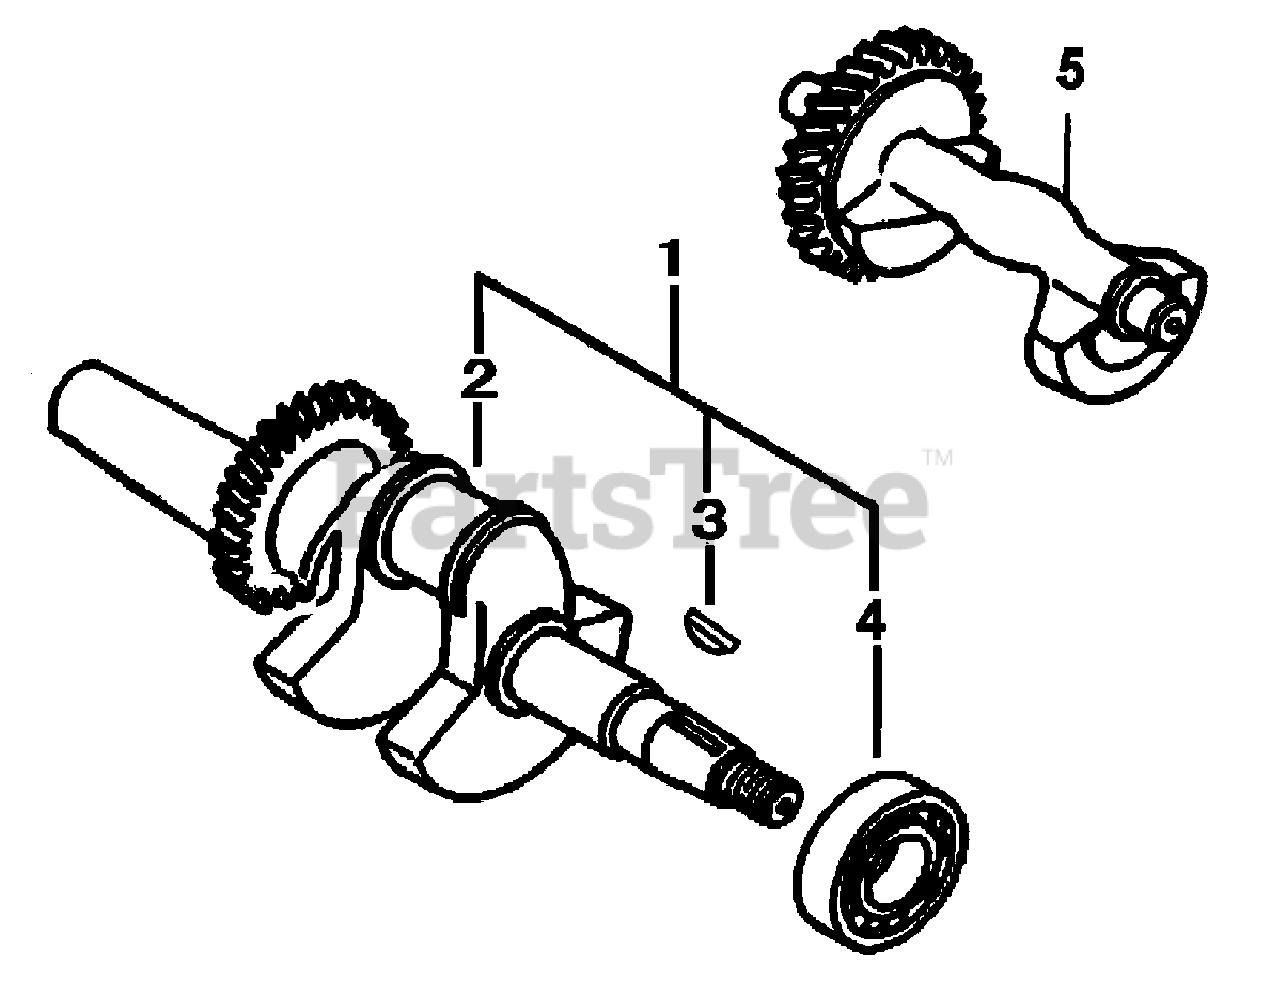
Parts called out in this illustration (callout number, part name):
1	CRANKSHAFT COMPLETE
2	CRANKSHAFT
3	KEY, SPECIAL WOODRUFF
4	BEARING, RADIAL BALL, 6207
5	WEIGHT, BALANCER
